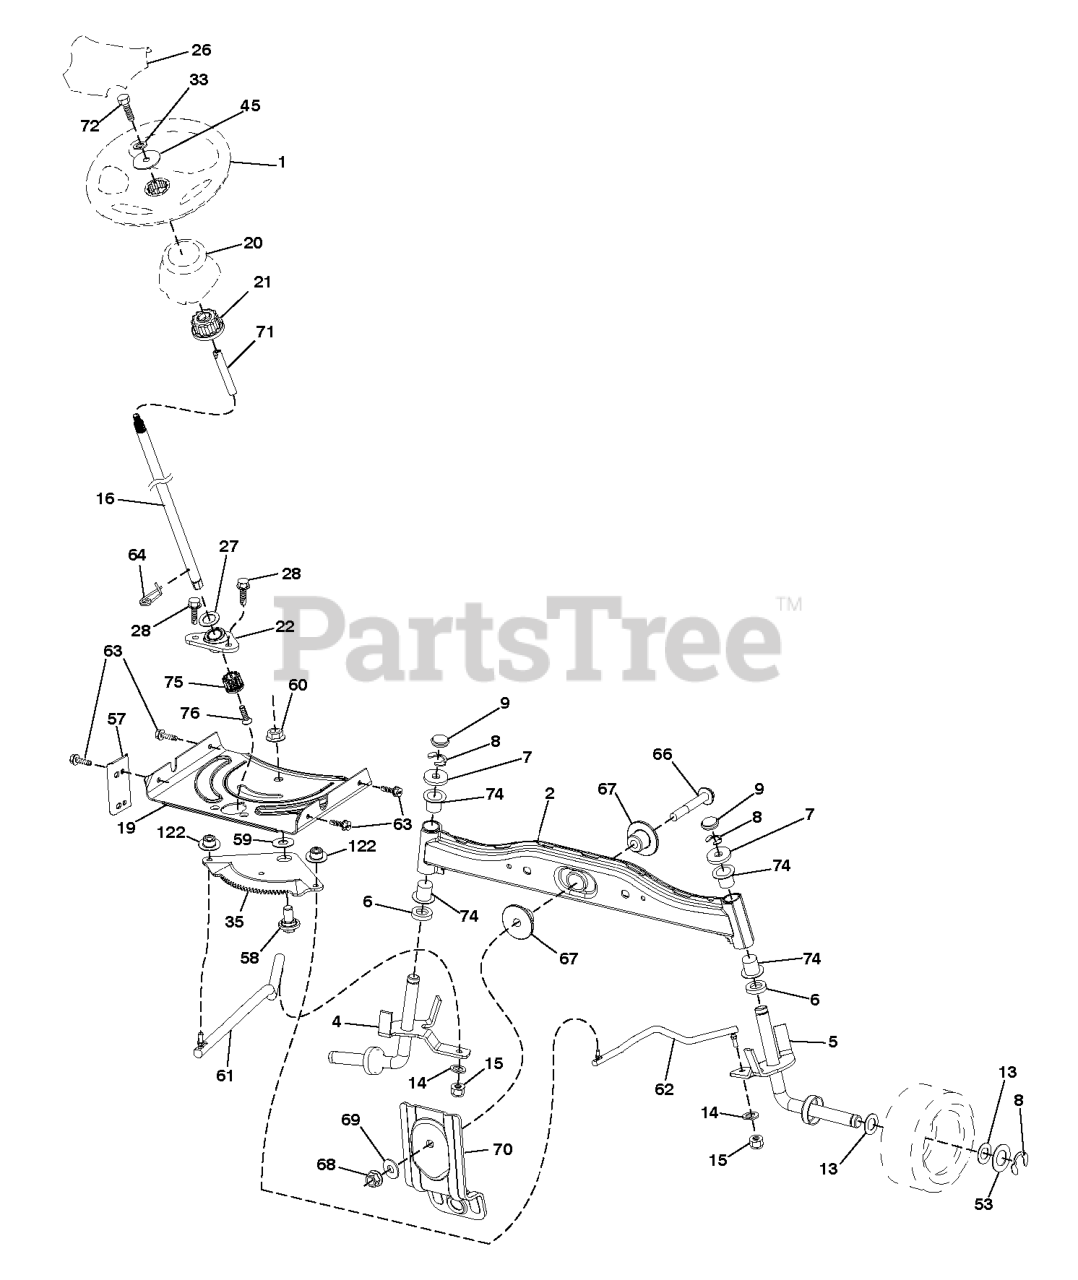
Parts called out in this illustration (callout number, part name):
1	WHEEL.STEERING.HUSQ.PREM.HRDRM
1	Service Kit
2	AXLE HALF ASM-WELDED
4	SPINDLE.WELDED.LH.15"TEX
5	SPINDLE.WELDED.RH.15"T
6	WASHER THRUST
9	CAP.SPINDLE.BLACK
15	NUT CROWNLOCK 3/8-24
16	3 HIGH.SHAFT-ZINC.PLATED
19	PLATE.STEER.DDL.NLT/NG
20	STEERING.BOOT.HUSQ.LT
21	ADAPTER, WHEEL STNG..
22	BEARING.SHAFT.STEER.LOWER.625
26	Steering
26	INSERT.CAP.WHL.STRG.HUSQ.PREM
28	SCREW, 3/8-16X3/4
33	WASHER SPRING LOCK WASHER WITH
35	GEAR.SECTOR.PLATE.DDL.
53	WASHER.HARDENED
57	BRACKET.UPSTOP.TEX
58	BOLT.SHOULDER.SECTOR.P
59	WASHER.THURST.SECTOR.S
60	NUT FLANGE LOCK 5/8-11
61	DRAGLINK.LH.BALLSTUD.D
61	Links
62	Links
62	DRAGLINK.RH.BALLSTUD.D
63	SCREW
64	RETAINER.CLIP.SPRING.S
66	BOLT HEX FGHD 7/16-14 X 3 SERR
67	BUSHING.PM.FRONT AXLE
68	NUT.LOCK.FLANGE.7/16
69	WASHER.1.5X.505X.118
70	BRACKET.FRT.DECK.SUSP.RR.MT431
71	SHAFT.EXTEN.STRG.SPLINE
74	BEARING.STEERING.COLUMN
75	PINION.ZINC PLATED
76	SCREW HEAD SOCKET LRVB
122	CAP.GEAR.SECTOR.TEX
